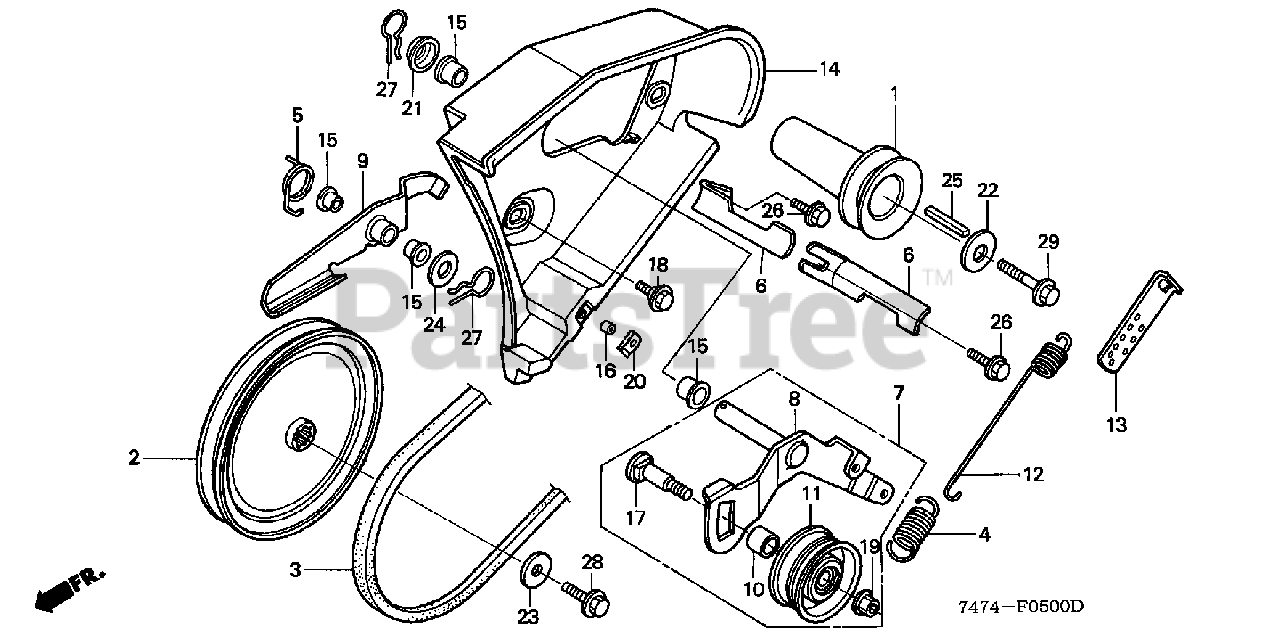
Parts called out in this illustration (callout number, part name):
1	PULLEY, DRIVE
2	PULLEY, DRIVEN
3	V-BELT (LA-38)
4	SPRING, TENSION ARM RETURN
5	SPRING, BRAKE ARM
6	STOPPER, BELT
7	ARM ASSY., AUGER TENSION
8	ARM, AUGER TENSION
9	ARM, AUGER BRAKE
10	COLLAR, ROLLER
12	SPRING, BELT TENSION
13	PLATE A, ADJUSTING
14	COVER (INNER)
15	BUSH, BLADE HOLDER
16	COLLAR, CHUTE GUIDE
17	BOLT, TENSION ROLLER
18	BOLT, FLANGE (6MM) (BLACK)
19	NUT, SELF-LOCK (8MM)
20	NUT, SPRING (6MM)
21	WASHER, SPECIAL (13MM)
22	WASHER (8MM)
23	WASHER (8MM)
24	WASHER, TANK SETTING
25	KEY (5X5X33)
26	BOLT-WASHER (8X16)
27	PIN, LOCK (10MM)
28	BOLT, FLANGE (8X20)
29	BOLT, FLANGE (8X25)
